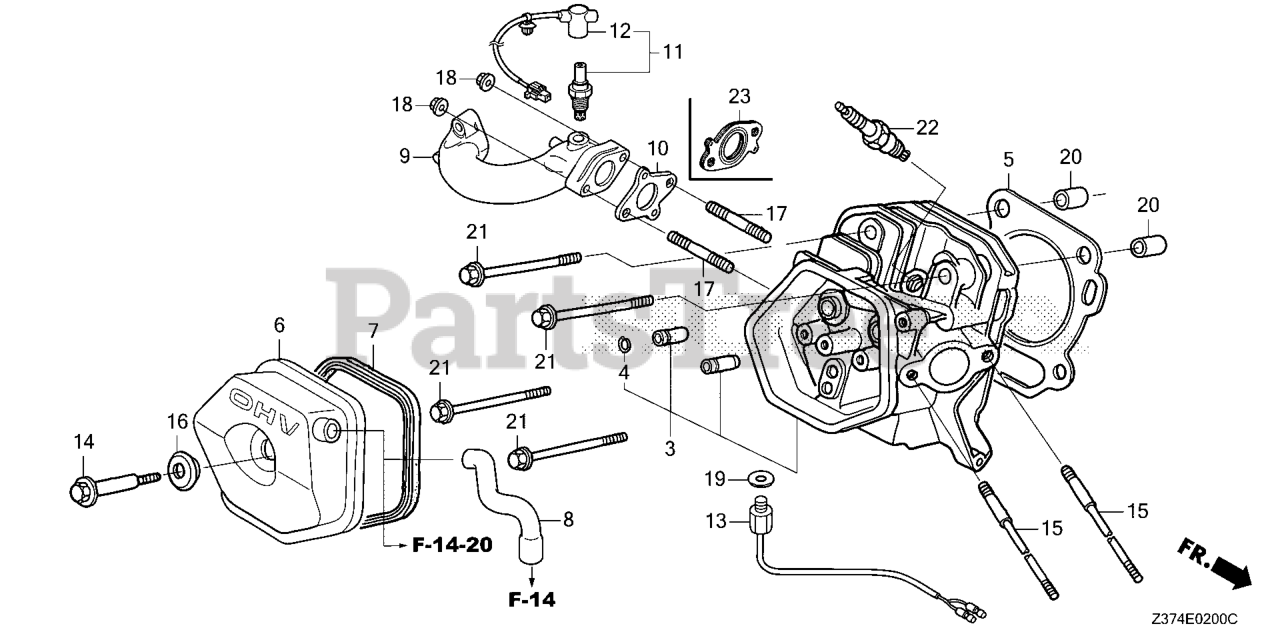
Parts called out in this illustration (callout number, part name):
3	CYLINDER HEAD
4	CLIP, VALVE GUIDE
5	GASKET, CYLINDER HEAD (NIPPON LEAKLESS)
6	COVER, HEAD (BREATHER TUBE JOINT)
7	GASKET, CYLINDER HEAD COVER
8	TUBE, BREATHER
11	SENSOR, OXYGEN
12	WIRE, OXYGEN SENSOR
13	SENSOR ASSY., TEMPERATURE
14	BOLT, HEAD COVER
15	BOLT, STUD (8X126.5)
16	WASHER, HEAD COVER
17	BOLT 2, STUD (8X32)
18	NUT, FLANGE (8MM)
19	WASHER, PLAIN (8MM)
20	PIN A, DOWEL (12X20)
21	BOLT, FLANGE (10X80)
22	SPARK PLUG (BPR6ES) (NGK)
23	GASKET, EX. PIPE
